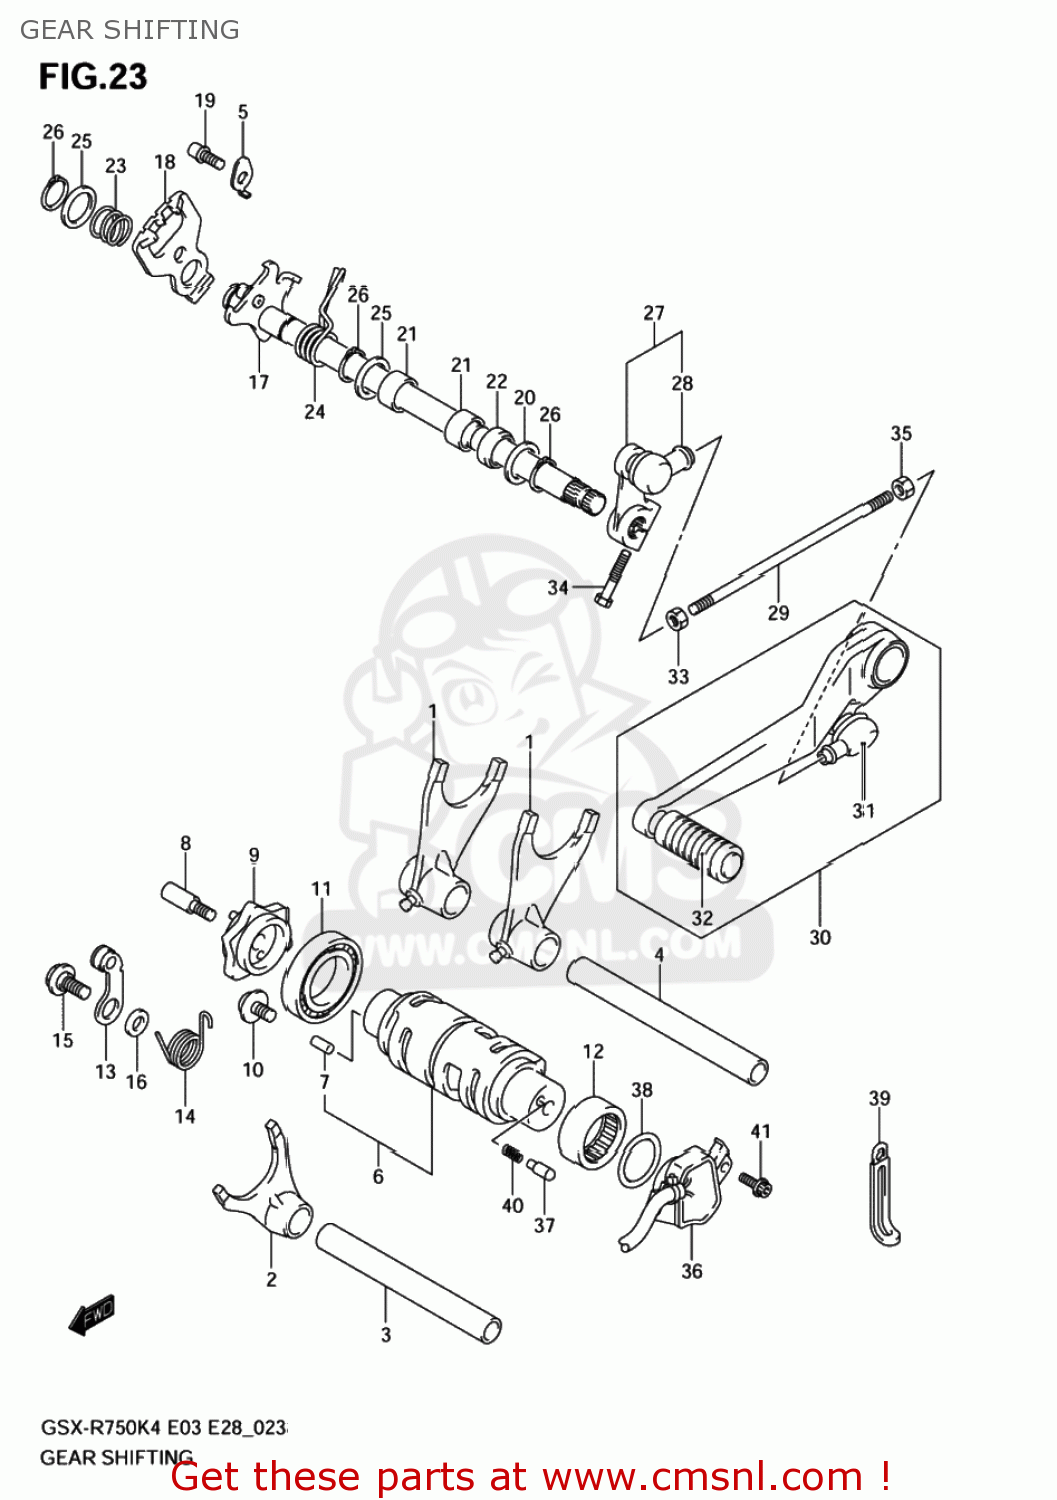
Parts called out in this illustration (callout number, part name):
1	FORK,GEAR SHIF
2	FORK,GEAR SHIF
3	SHAFT,GEAR SHIFT FORK
4	SHAFT,GEAR SHIFT FORK NO.1
5	RETAINER,GEAR SHIFT FORK SHAFT
6	CAM,GEAR SHIFT
7	PIN
8	BOLT,GEAR SHIF
9	PLATE,GEAR SHIFT CAM
10	SCREW(6X12)
11	BEARING(25X47X8)
12	BEARING(25X32X12)
13	STOPPER,SHIFT CAM
14	SPRING,SHIFT CAM STOPPER
15	BOLT(6X14.3)
16	WASHER
17	SHAFT,GEAR SHIFT
18	PLATE,GEAR SHIFT CAM DRIVE
19	STOPPER,GEAR SHIFT ARM
20	WASHER(14X29X0.8)
21	BEARING(14X20X12)
22	SEAL,OIL(14X22X6)
23	SPRING
24	SPRING
25	SHIM(14X22X1)
26	CIRCLIP
27	ARM,GEAR SHIFT LINK
28	COVER,DUST
29	ROD,GEAR SHIFT LINK
30	LEVER ASSY,GEAR SHIFT
31	COVER,DUST
32	RUBBER,GEAR SHIFT PEDAL
33	NUT
34	BOLT
35	NUT
36	BASE ASSY,GEAR SHIFT TERMINAL
37	PIN(5X15.5)
38	O RING(D:2.4,ID:25.7)
39	CLAMP(L:45)
40	SPRING
41	BOLT(5X16)
